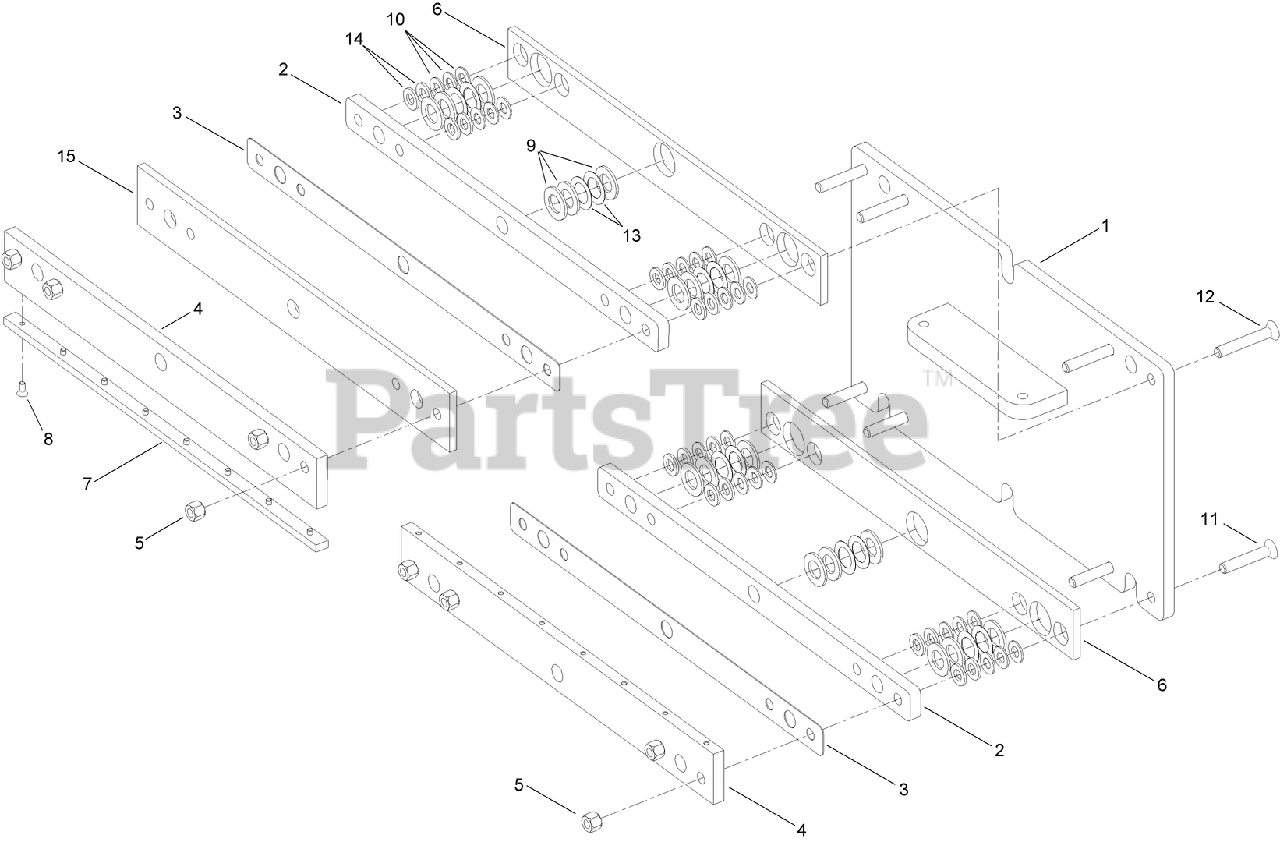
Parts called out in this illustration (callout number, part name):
1	MOUNT-SLIDE
2	PLATE-SPACER
3	PLATE-SLIDE
4	PLATE-LIP
5	NUT-HEX, CENTER LOCK
6	STRIP-WEAR
7	STRIP-WEAR
8	SCREW-HSFH
10	WASHER-FLAT
11	SCREW-HSFH
12	SCREW-HSFH
14	WASHER-FLAT
15	STRIP-ANTIFRICTION, FRONT
